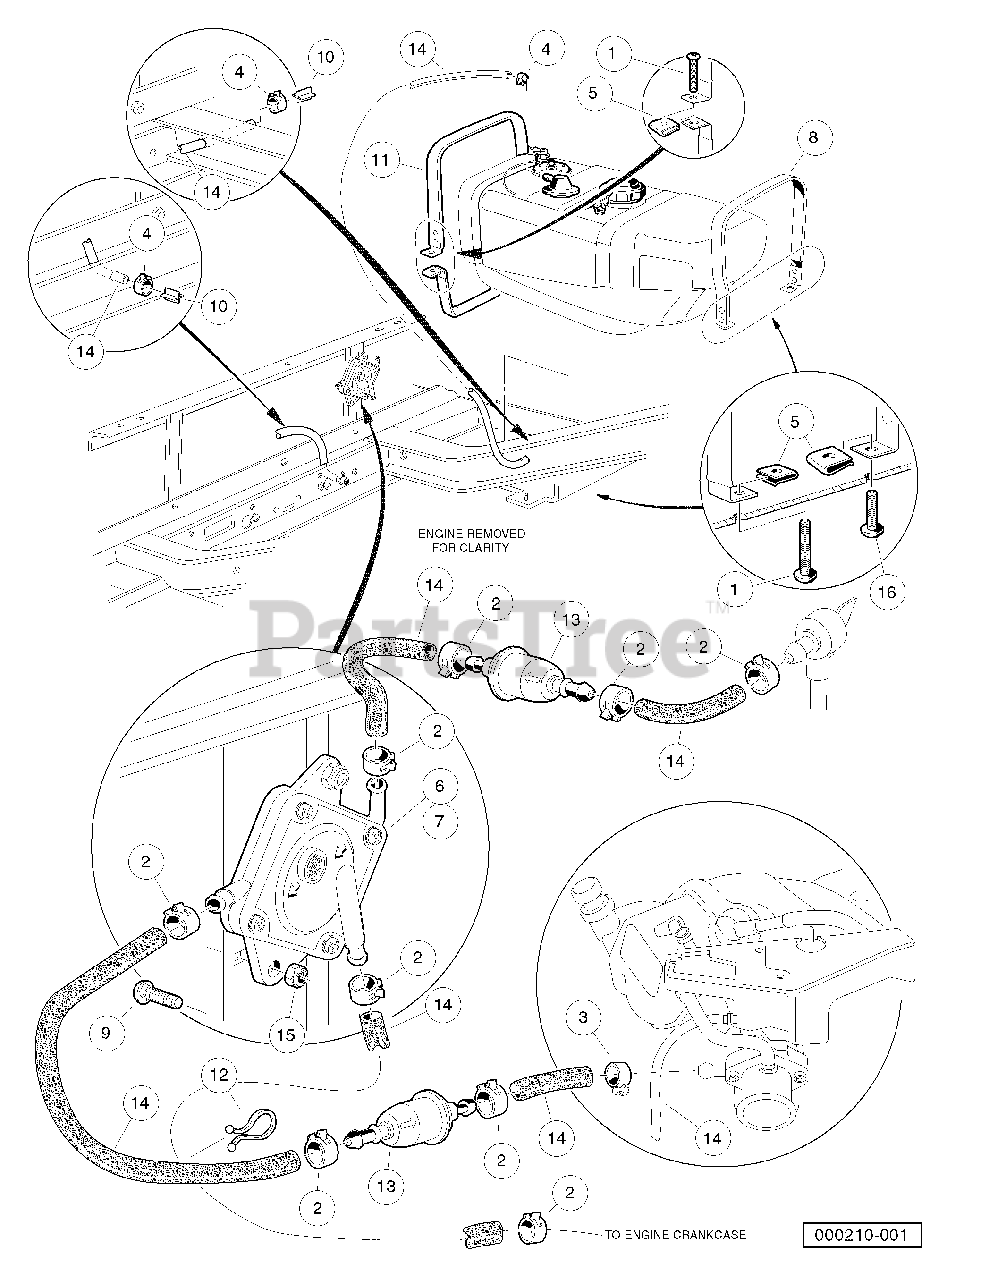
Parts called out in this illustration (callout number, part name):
1	Screw, 1/4-20 X 2.00 Phillips Truss-Head
2	Clamp, 0.460 Red Hose
3	Clamp, 3/8" Hose
4	Clamp, 0.301 ID Hose
5	Nut, 1/4-20 Speed
6	Pump, Impulse Fuel
7	Kit, Impulse Pump Rebuild
8	Fuel Strap Assembly Rear
9	Carriage Bolt
11	Fuel Strap Assy, Front
12	Clamp, Plastic Tie
13	Filter, Fuel, 30 Micron
15	Locknut, 1/4-20 Nylon Insert
16	Screw, 1/4-20 X 0.75 Truss-Head Machine
